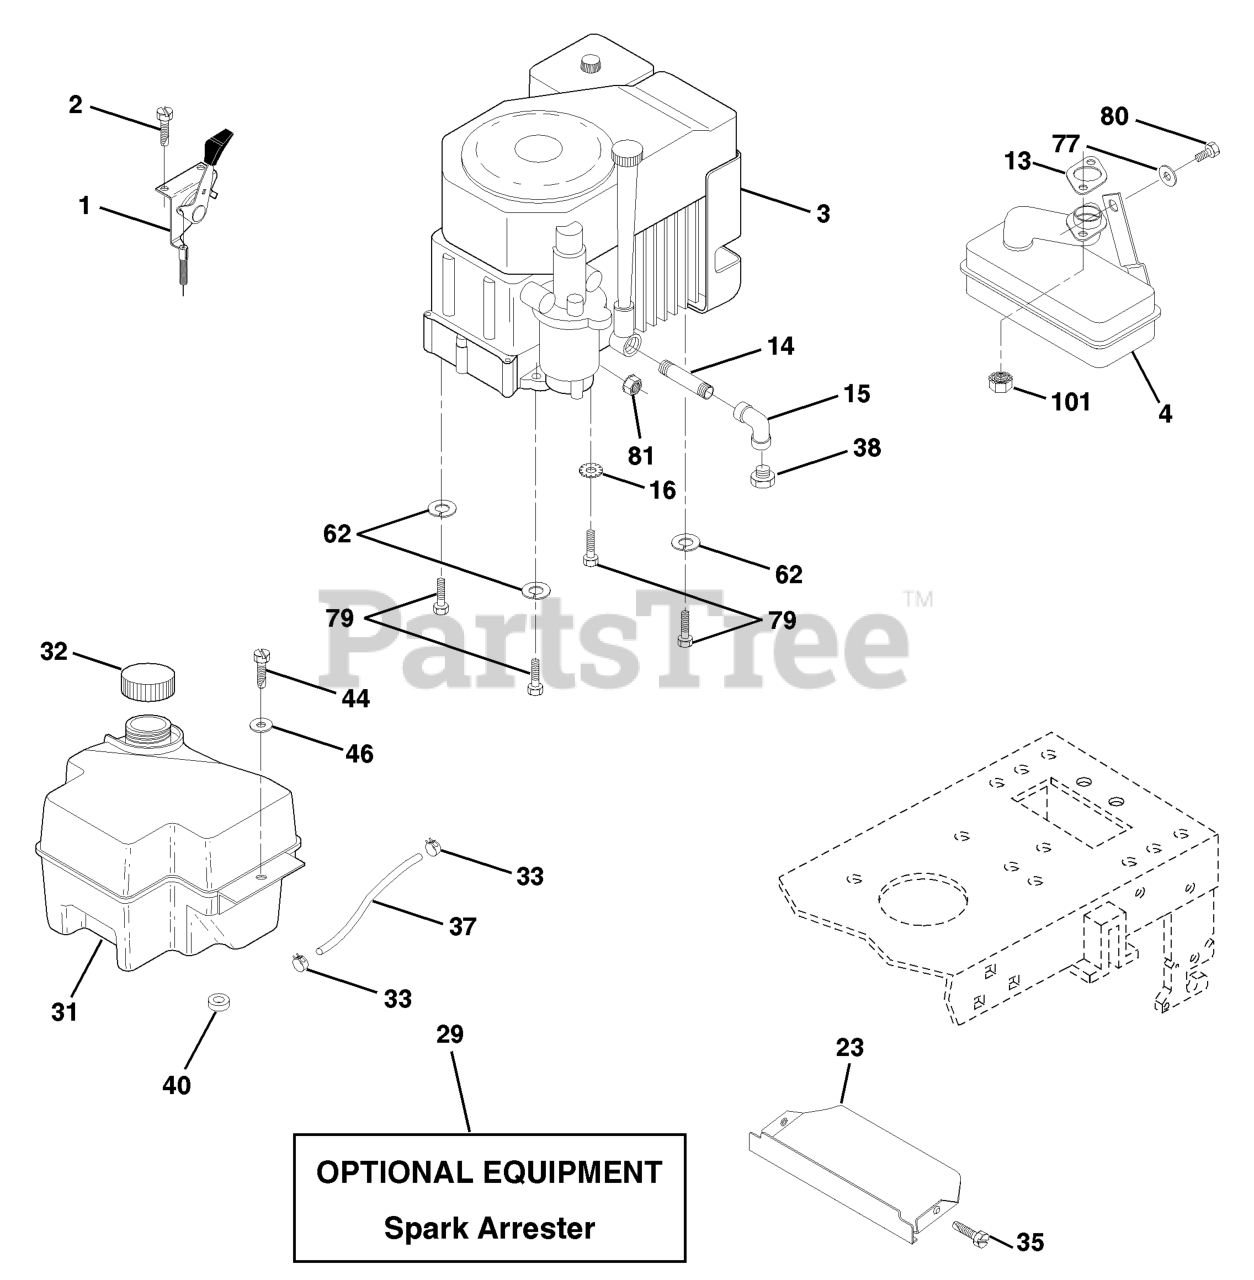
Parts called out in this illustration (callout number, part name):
1	CONTROL SWITCH 27 LH
2	SCREW LT
4	MUFFLER LT 12.5
13	KOHLER GASKET
14	Nipple Pipe 3/8 Npt X 3-1/2
15	ELBOW
16	WASHER EXT TOOTH LOCK 5/16
29	KIT.SPARK ARRESTOR 794945 B&S
31	FUEL TANK
32	FUEL CAP
33	HOSE CLAMP
35	SCREW.THDROL.5/16-18X3/4.TTY
37	LINE.FUEL.20
38	Plug Oil Drain
40	BUSHING.SNAP.NYL.BLK.
44	SCREW HEX CRT
46	WASHER
62	WASHER.LOCK.HVY.HLCL.SPR.5/16
77	WASHER
79	BOLT, HEX
80	Bolt Hex Hd 5/16-18 UNC x 1/2
81	NUT FLANGE 1/4-20 STARTER NUT
101	FLANGE NUT
